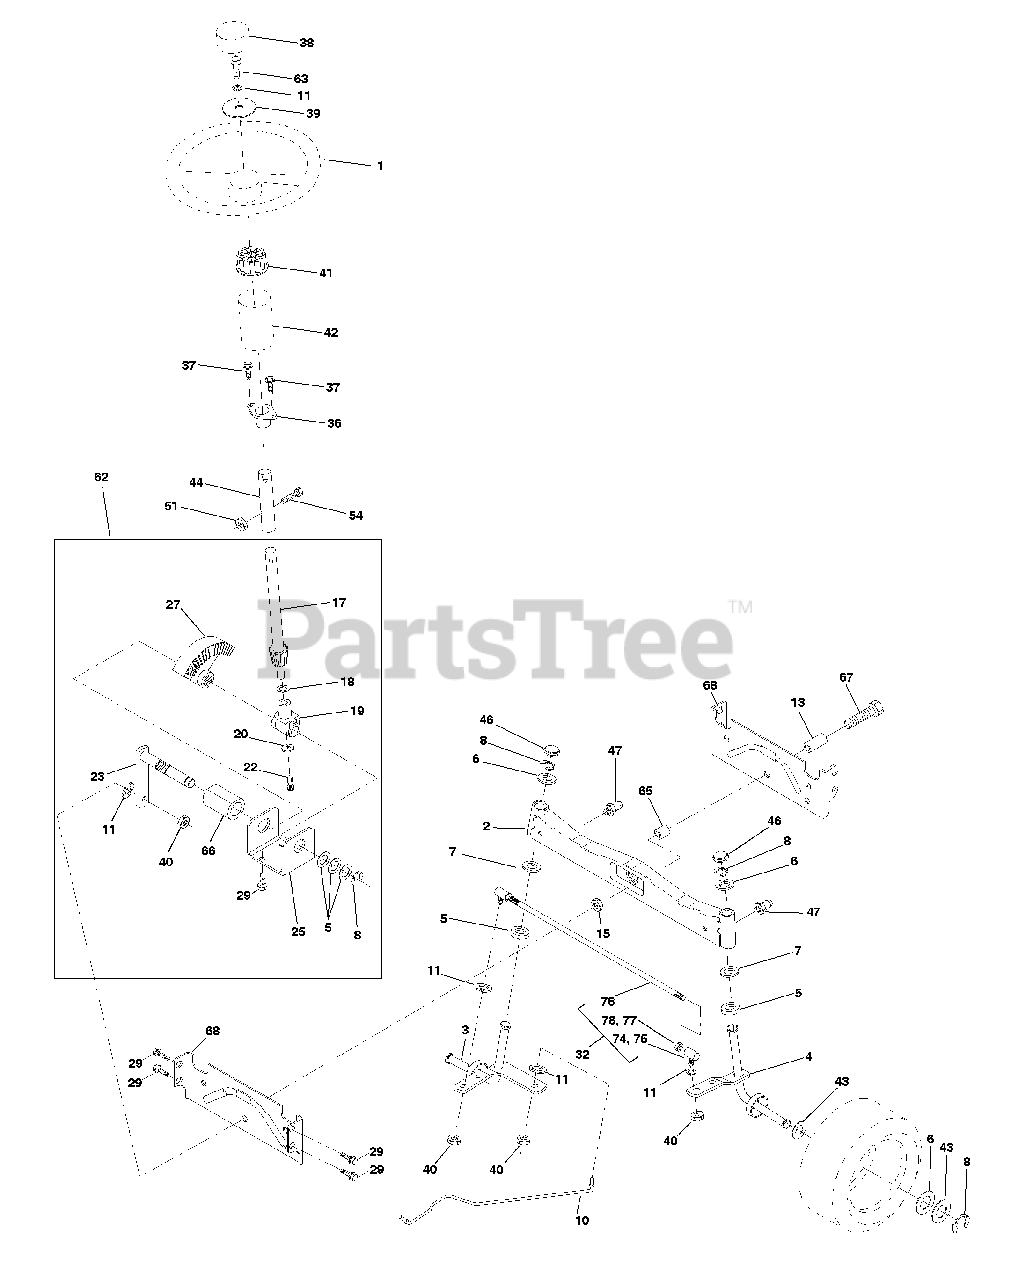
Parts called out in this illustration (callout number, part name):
1	Wheel Steering
2	Axle Front Cast Machined
3	Spindle Asm LH
4	Spindle Asm RH
5	Bearing Race Thrust Harden
6	Washer 25/32 X 1-5/8 X 16 Ga
7	Washer 27/32 X 1-1/4 X 16 Ga
8	Ring Klip #t5304-75
9	Bearing Col Strg Blk
10	Link Drag Extended Cast
11	Washer Lock Hvy Hlcl Spr 3/8
13	Bearing Axle STLT/GT
15	Nut Lock Flange 5/8-11 Unc
17	Shaft Asm Strg
18	Washer Thrust 515x 750x 033
19	Support Shaft
20	Washer Shim 1/4 X 5/8 X 062
22	Screw Hex Socket 1/4-20 x 5/8
23	Shaft Asm Pittman
25	Bracket Steering
27	Gear Sector
29	Screw Thdrol 3/8-16x3/4 Ty-tt
32	Rod Tie Ball J Adj VGT
36	Bushing Strg
38	Insert Cap Strg Wh Au
39	Washer 13/32 X 2-3/8 X 8 Ga
40	Lock nut
41	Adaptor Wheel Strg
42	Boot Steering Shaft
43	Washer 25/32 X 1 1/4 X 16 Ga
44	Extension Steering Shaft LR/LT
46	Cap Spindle Fr Top Blk
47	Fitting Grease
51	Nut Lock Hex w/Ins 5/16-18
54	Bolt Fin Hex 5/16-18 Unc x 1-1/4
62	Kit, Steering Assembly Svc
63	Bolt Fin Hex 3/8-16unc x 1 Gr. 5
65	Spacer Axle
66	Bearing Arm Pittman
67	Bolt, Fin Hex 5/8-11 UNC x 2-3/4
68	Axle, Brace
74	Joint Asm Ball Rh
75	Joint Asm Ball Lh
76	Rod Tie Ball J Adj
77	Nut Hex Jam 3/8-24 Unf Lh
78	Nut Hex Jam 3/8-24 Unf
